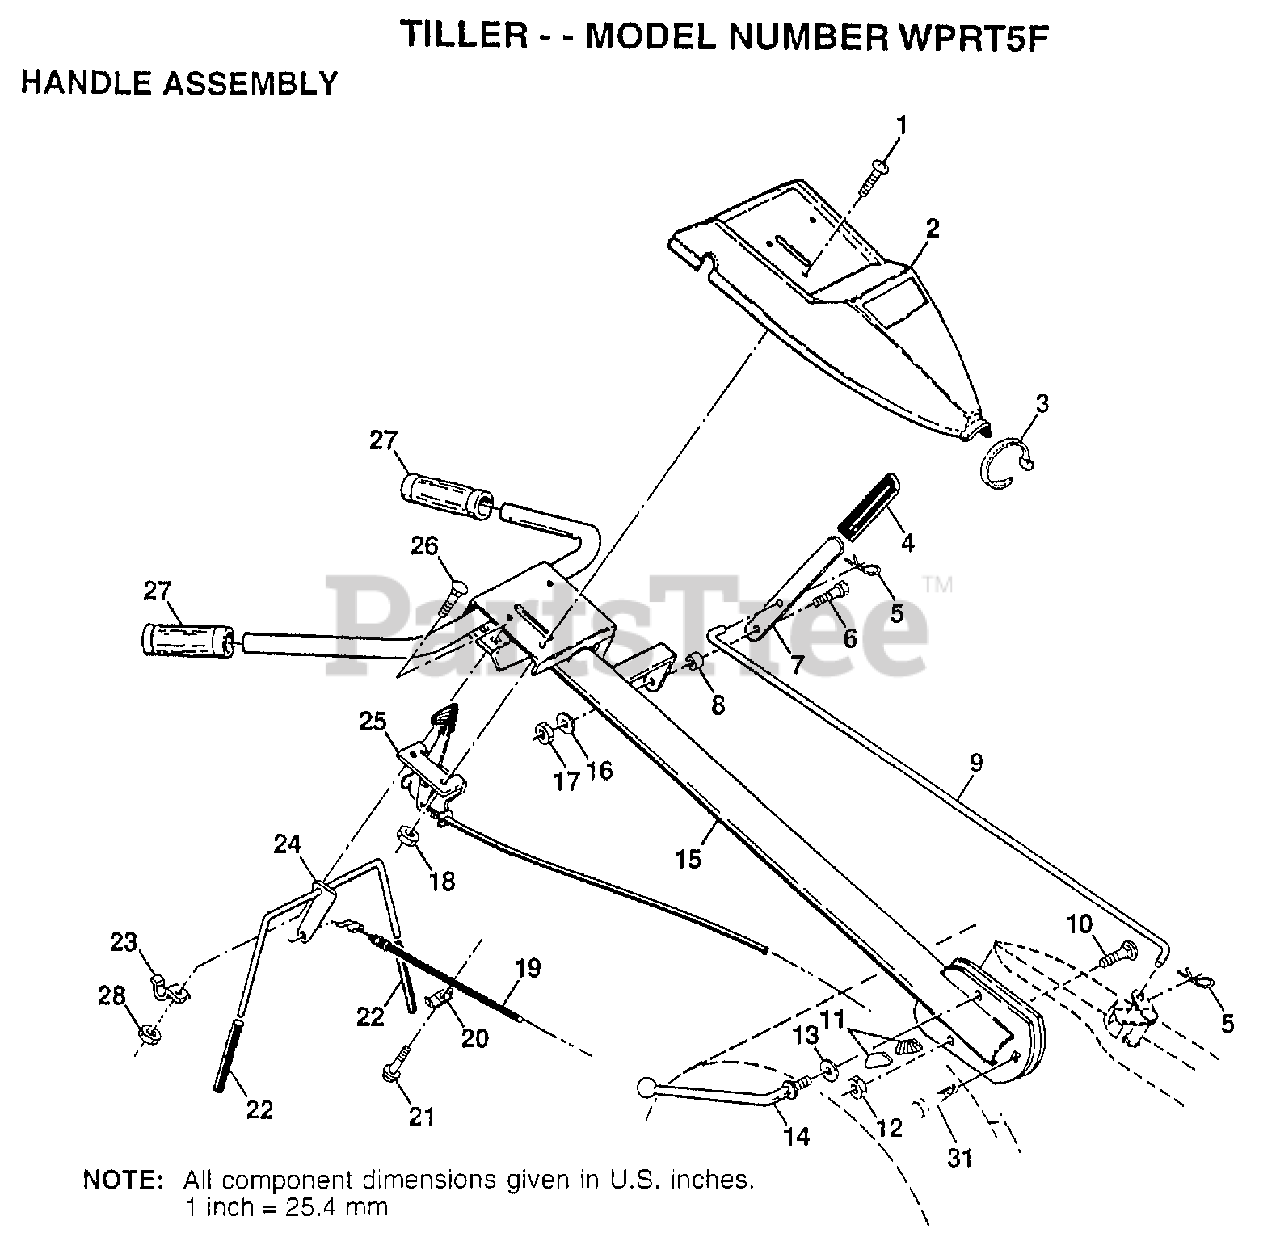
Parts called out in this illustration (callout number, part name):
1	SCREW.PNHD.10-24
2	"PANEL,CONT TI"
3	TIE CABLE CRT
4	GRIP T
5	RETAINER M
6	SHOULDER BOLT ST
7	SHIFT HANDLE CRT
8	GROMMET CRT
9	SHIFT ROD CRT
10	BOLT D
11	LOCK CRT
12	LOCKNUT
13	WASHER CRT
14	LEVER LOCK CRT
16	LOCKWASHER
19	CABLE.CLUTCH.48.Z
20	CONDIUT CLIP T
22	GRIP BAR CRT
24	"ASSY CONTROL, BAR"
25	"CONT,THROTTLE"
26	BOLT
28	NUT
31	BOLT PIVOT
